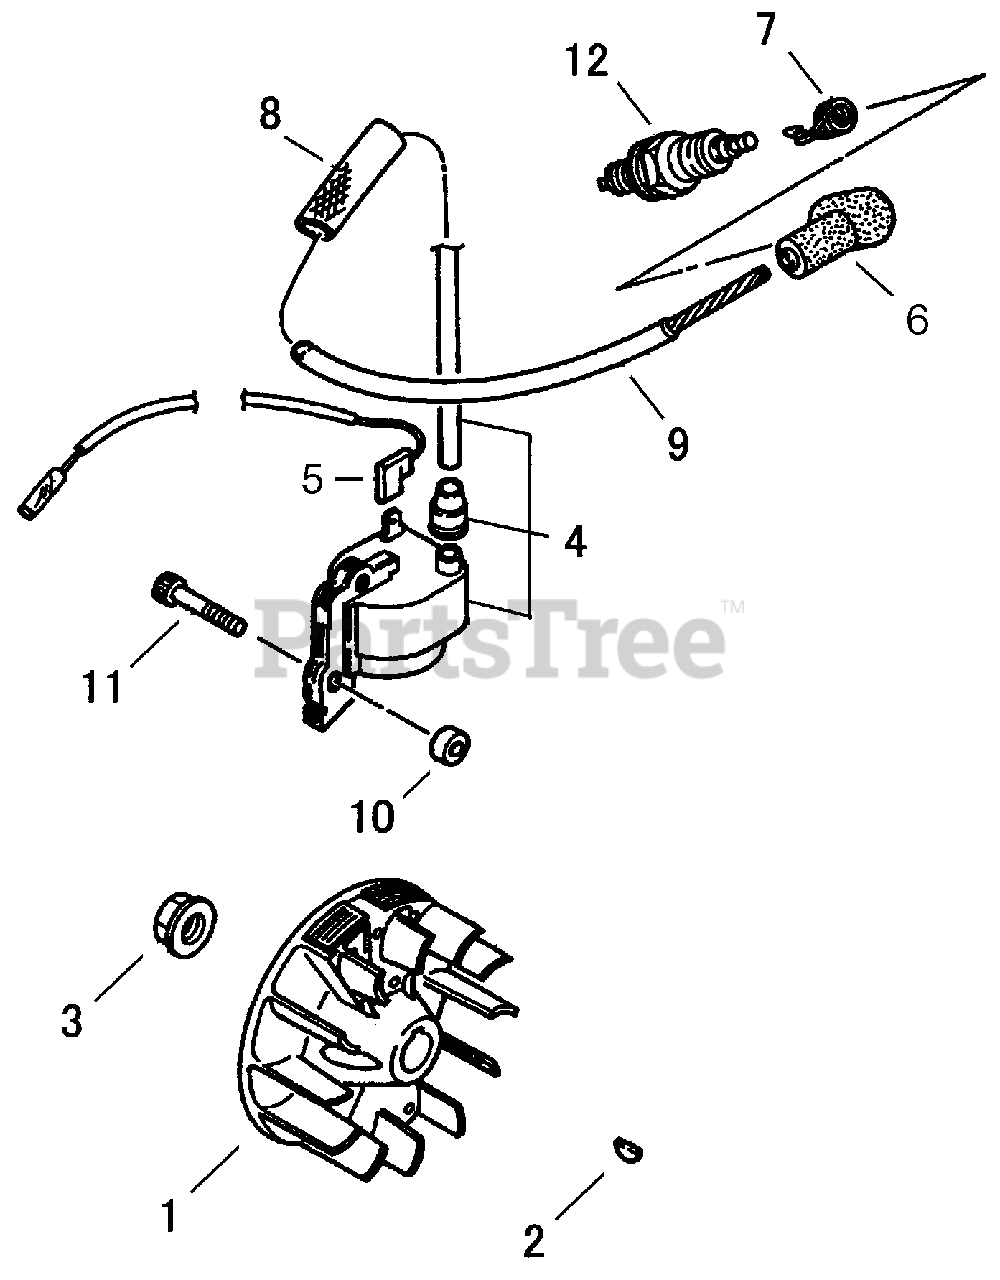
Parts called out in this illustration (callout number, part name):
1	FLYWHEEL
2	KEY - 3X10
3	NUT - 8
4	IGNITION COIL ASSY
5	LEAD - IGNITION
6	CAP, SPARK PLUG
7	TERMINAL, SPARK PLUG CAP
8	TUBE, INSULATOR
9	SLEEVE, INSULATOR
10	INSULATOR
11	SCREW - 4X26
12	SPARK PLUG -- BMR-6A
